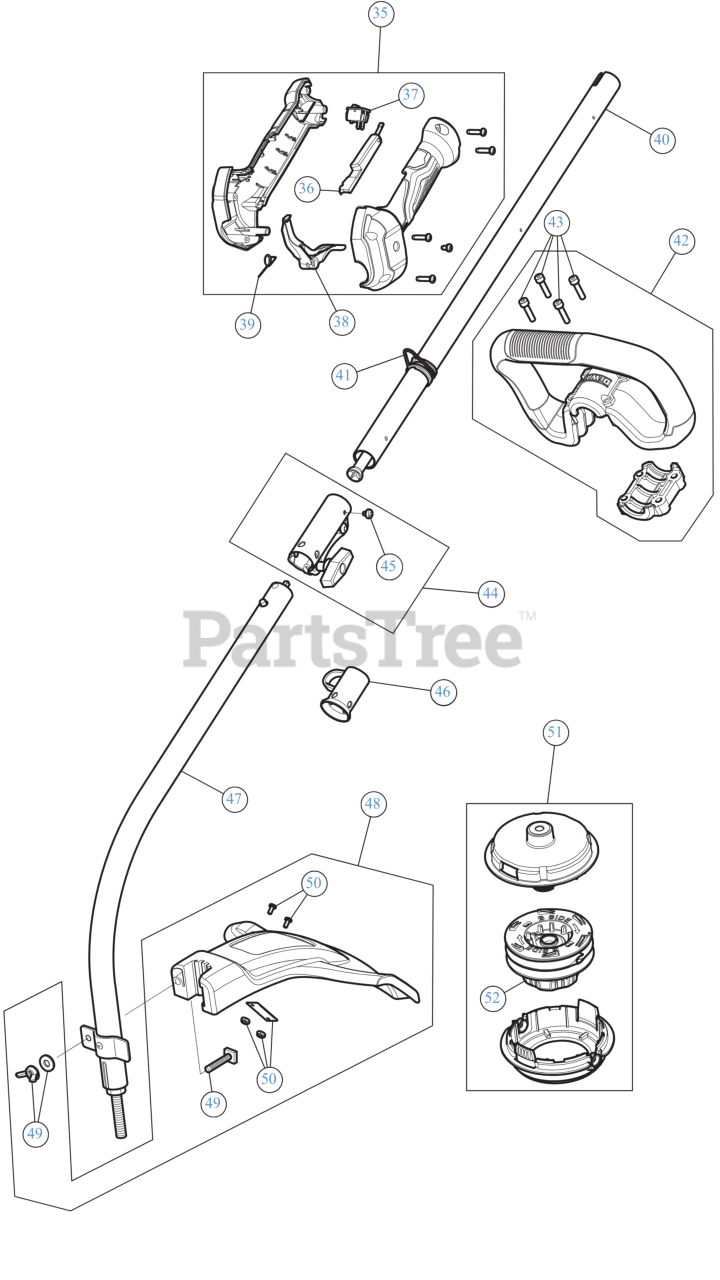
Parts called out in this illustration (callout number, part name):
35	THROTTLE GRIP
36	THROTTLE LOCK LEVER
37	SW, MOMENTARY ON/O
38	THROTTLE TRIGGER
39	TRIGGER SPRING
40	UPPER DRIVE SHAFT
41	CLAMP-SHOULDER STR
42	HANDLE
43	HANDLE BOLT
44	CLICK LINK
45	SCREW, 10-32X.250 TA
46	HANGER
47	LOWER SHAFT HOUSING
48	GUARD ASSEMBLY
49	BLADE GUARD MOUNTING HARDWARE
50	ASSEMBLY, BLADE
51	CUTTING HEAD
52	BUMP KNOB
